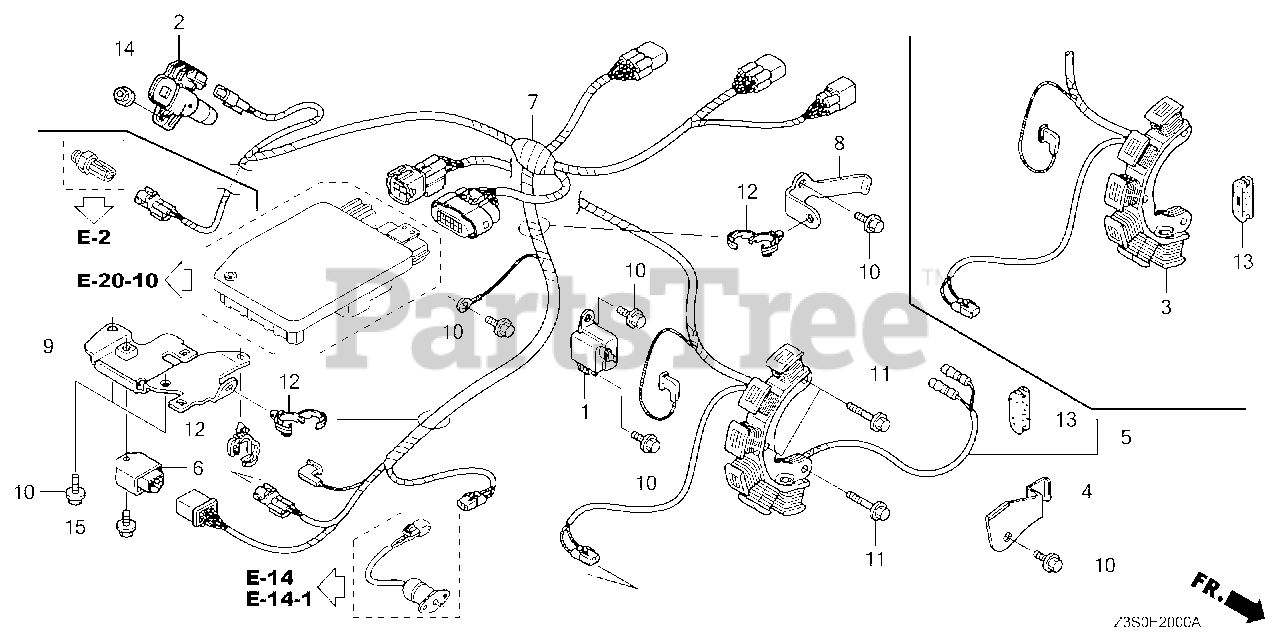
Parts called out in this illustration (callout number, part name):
1	COIL ASSY., PULSER
2	COIL, IGNITION
4	CLAMP, WIRE
5	COIL ASSY., CHARGE (3A)
6	RECTIFIER ASSY.
7	WIRE HARNESS ASSY., ENGINE
8	BRACKET, HARNESS CLIP (A)
9	BRACKET, HARNESS (C)
10	BOLT, FLANGE (6X14)
11	BOLT, FLANGE (6X32)
12	CLIP, HARNESS
13	GROMMET, CORD
14	NUT, FLANGE (6MM)
15	BOLT, FLANGE (6X12) Use from Engine SN 2086984.
